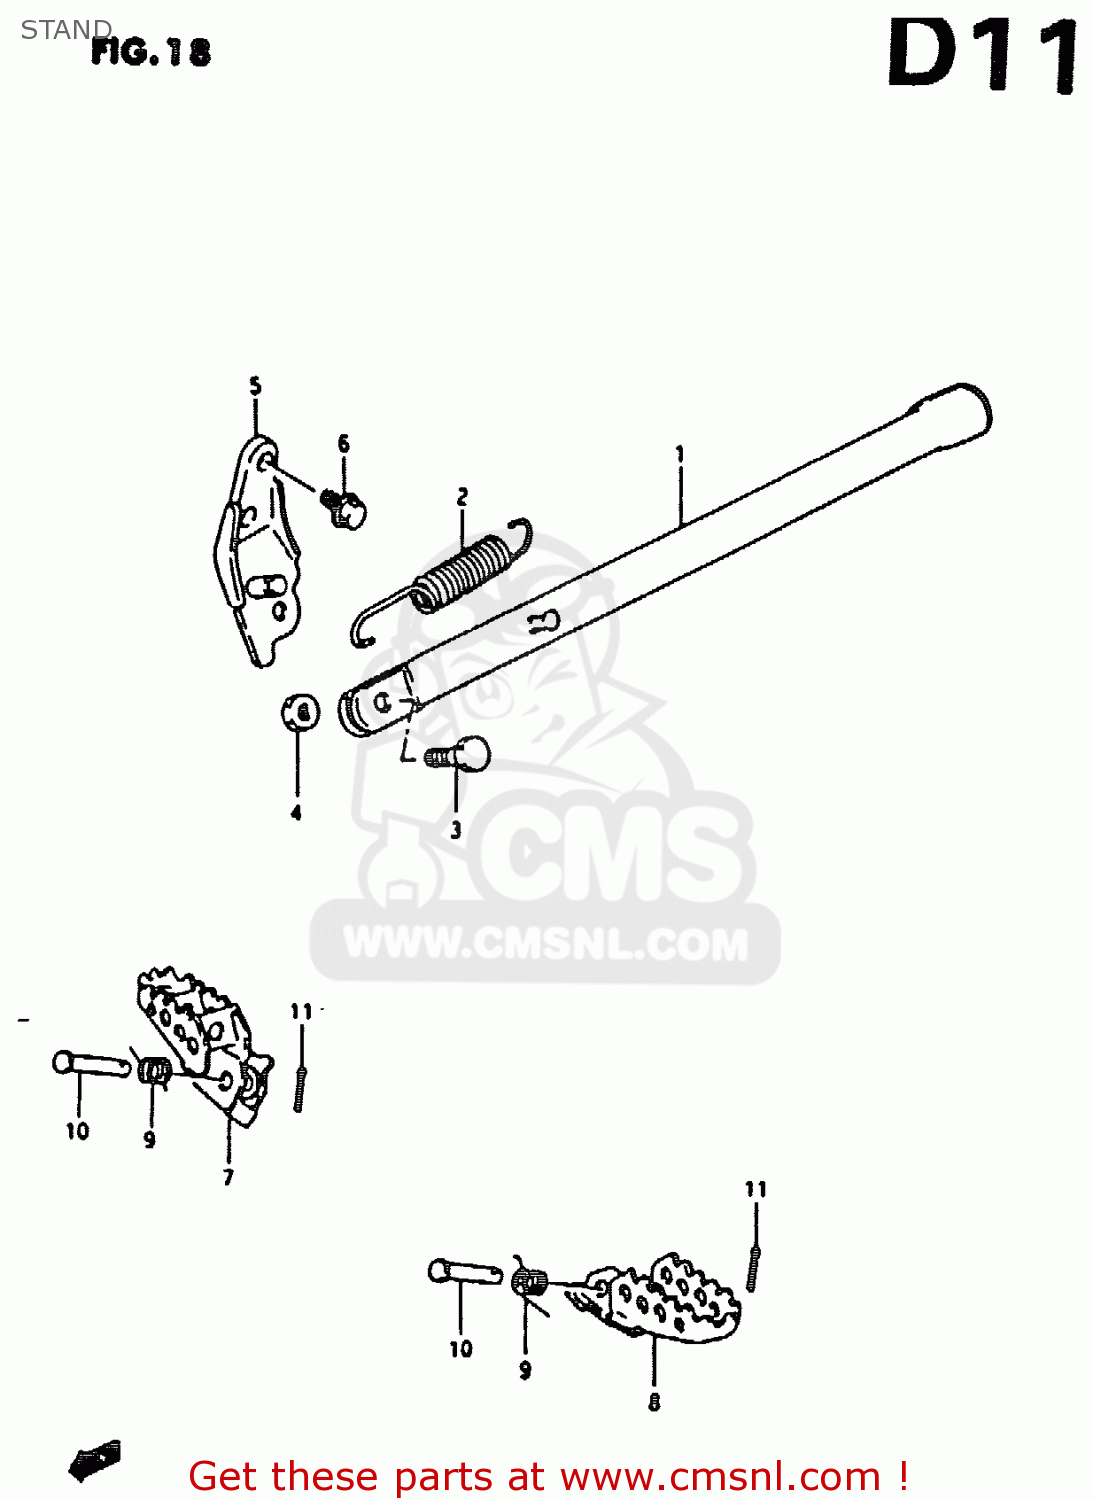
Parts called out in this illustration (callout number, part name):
1	STAND,SIDE
2	SPRING
3	BOLT(8X25)
4	NUT
5	BRACKET,SIDE STAND
6	BOLT
7	FOOTREST COMP,FRONT,RIGHT
8	FOOTREST COMP,FRONT,LEFT
9	SPRING
10	PIN
11	PIN
